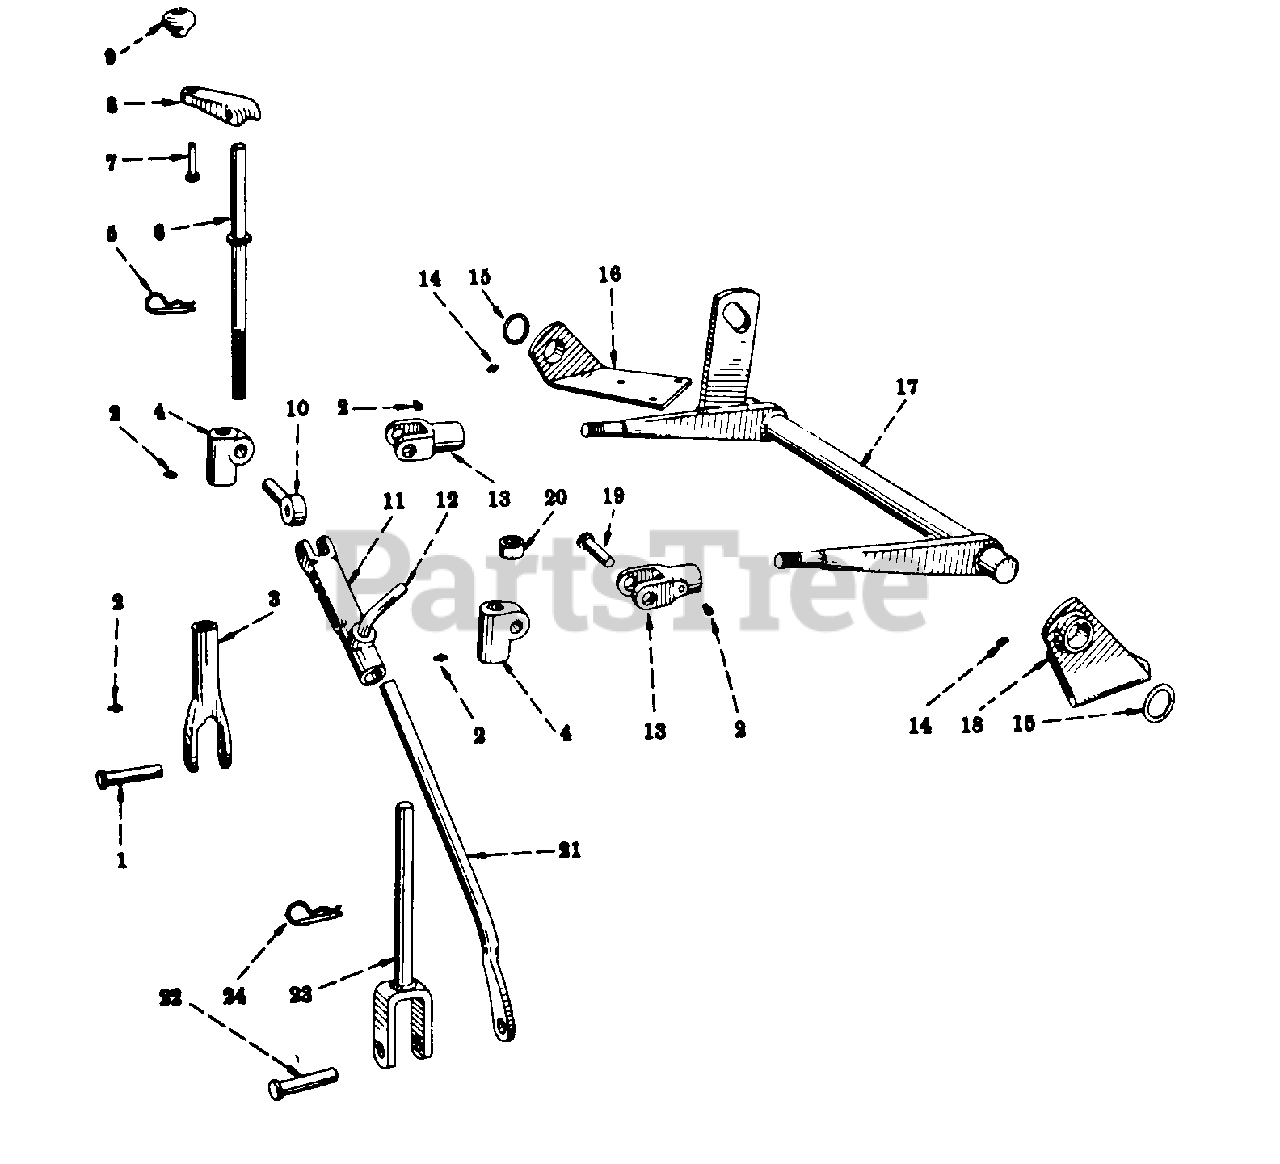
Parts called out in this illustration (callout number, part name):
1	PIN, 3/4 X 3 STD-HD DRILLED
2	FITTING, 1/8-27 STR LUB
3	HOUSING, LEVELING SCREW
4	SWIVEL, LATERAL LINK UPPER
5	PIN ASSY, QUICK-ATTACHABLE COT
6	SCREW ASSY, LEVELING
7	PIN, 1/2 X 2-9/16 ROLL
8	HANDLE, LEVELING SCREW
9	KNOB, LEVELING SCREW HANDLE
10	SWIVEL, DIAGONAL LINK
11	STOP, DIAGONAL LINK
12	BOLT, DIAGONAL LINK STOP LOCK
13	SWIVEL, ROCKSHAFT ARM
14	FITTING, 1/4-28 STR LUB
15	PLATE ASSY, ATTACHING ROCKSHAFT LH
16	ROCKSHAFT ASSY
17	WASHER, 1-17/32 X 2 X 16 GA
18	PLATE ASSY, ATTACHING ROCKSHAFT RH
19	PIN, 3/4 X 3-1/16 STD-HD DRILLED
20	COLLAR, LATERAL LINK
21	LINK, DIAGONAL
22	PIN, 3/4 X 3-3/8 STD-HD DRILLED
23	LINK ASSY, LATERAL
24	PIN ASSY, QUICK-ATTACHABLE COT
